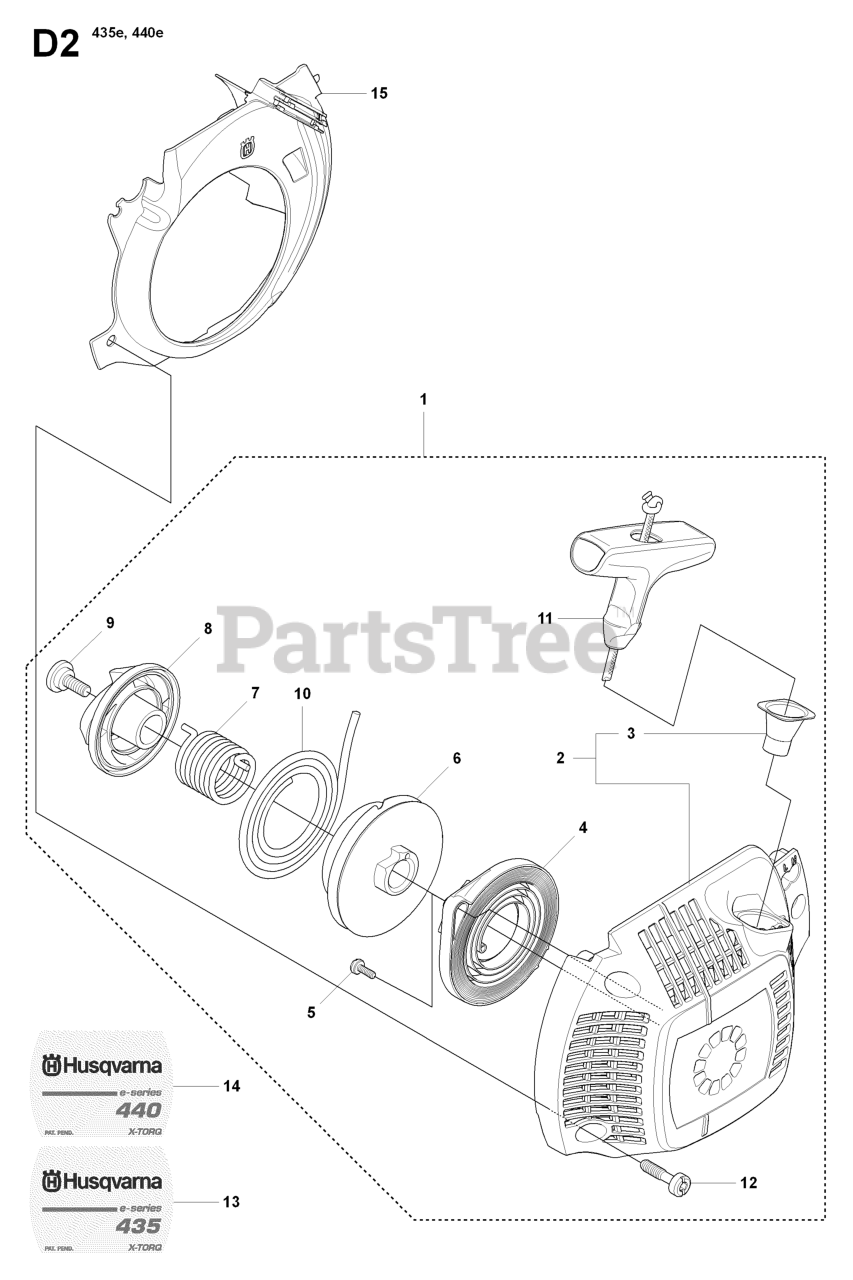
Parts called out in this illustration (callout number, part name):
1	STARTER ASSY
2	STARTER HOUSING
4	SPRING CASSETTE ASSY
6	STARTER PULLEY
10	STARTER ROPE
13	LABEL 435 STARTER
14	LABEL 440 STARTER
15	%COOLING AIR CONDUCTOR
